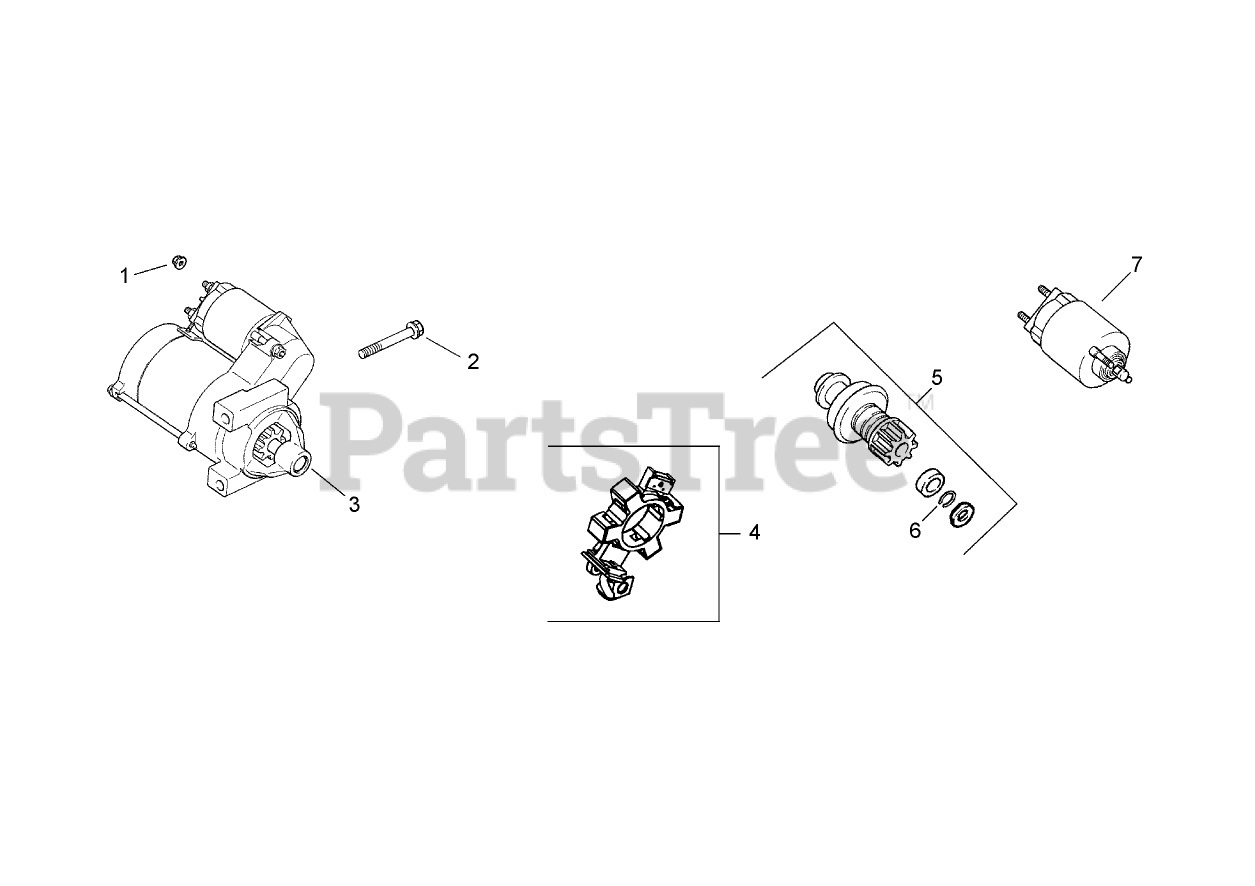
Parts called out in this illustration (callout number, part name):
1	NUT-FLANGE (M8X1.25)
2	SCREW-FLG (M8X1.25X80)
3	Starter Solenoid Shift ASM (Includes 4-7)
4	BRUSH HOLDER KIT
5	Pinion Drive Kit (Includes 6)
6	RING-RETAINING
7	Solenoid Kit
